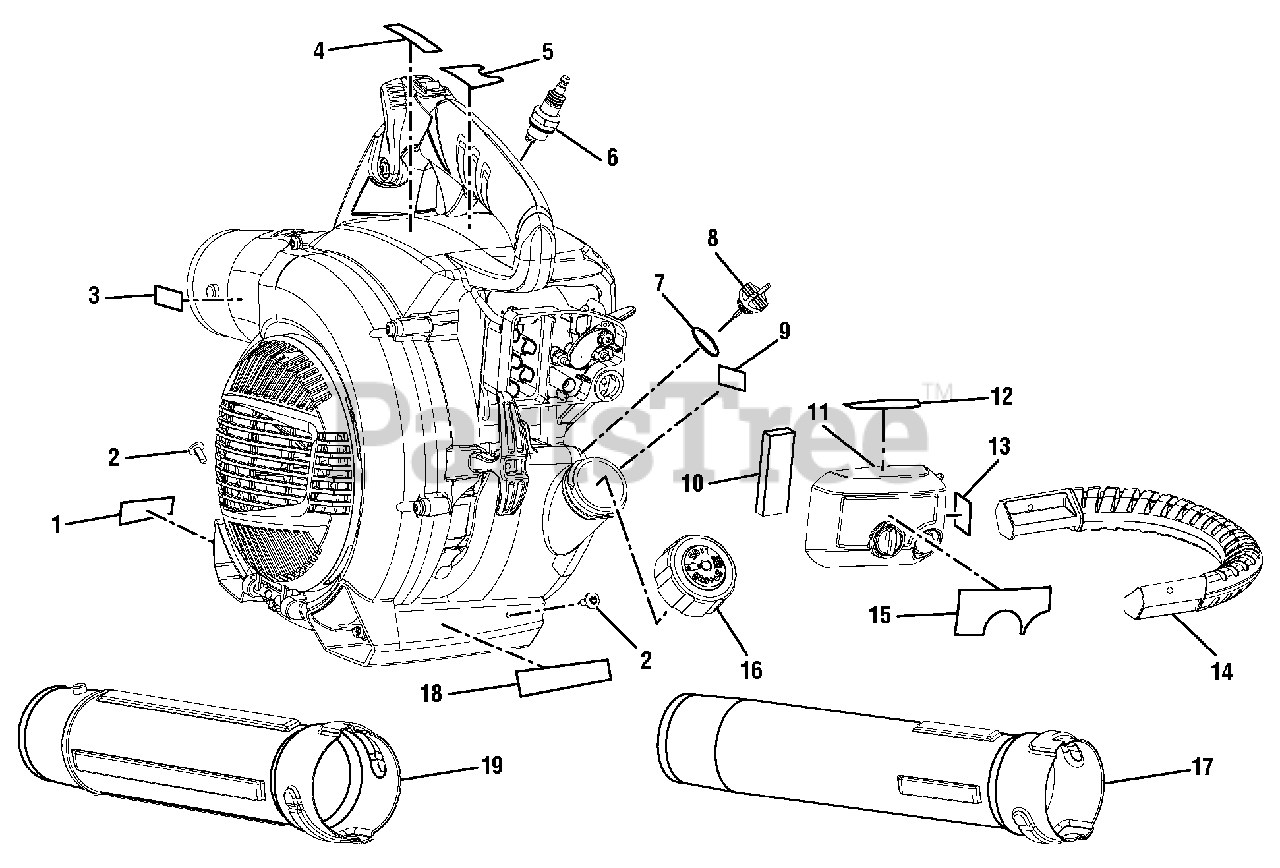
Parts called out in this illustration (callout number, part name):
1	Combustion Warning Label
2	Screw (#10-14 x 1/2 in., T25 Torx Truss Hd. T.F.)
3	Logo Label
4	Warning Label
5	Logo Label
6	Spark Plug (Champion RY4C)
8	Oil Fill Cap w/Dipstick
9	Add Oil Label
11	Air Filter Cover
12	Stop Label
13	Run/Start Label
15	Starting Label
16	Fuel Cap Assembly
17	Sweeper Nozzle
18	No Mix Label
19	Upper Blower Tube
